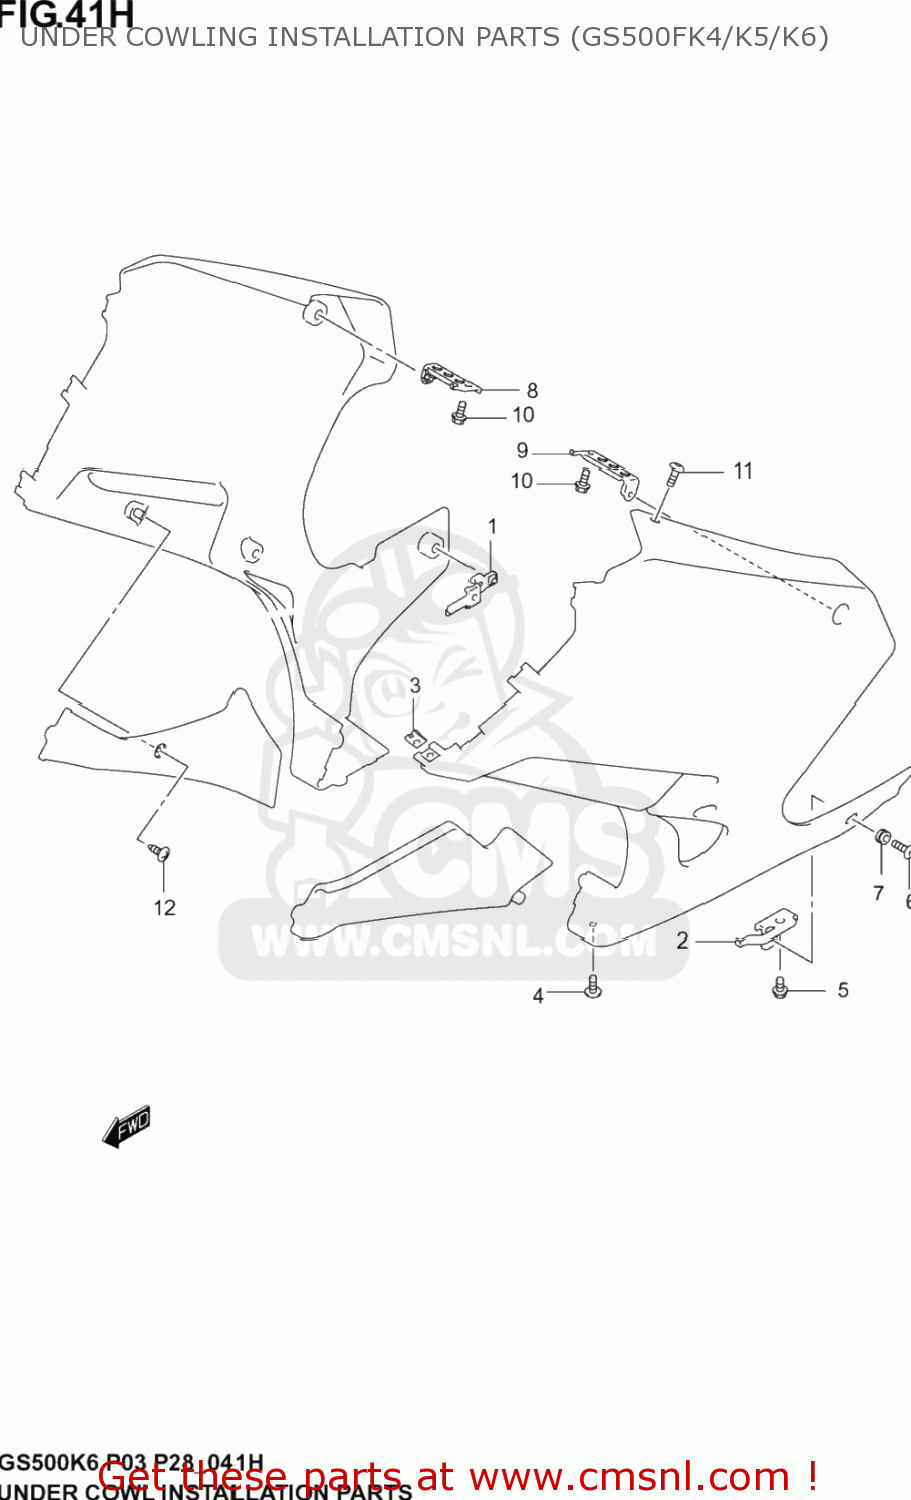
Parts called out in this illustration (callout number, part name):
1	BRACKET,LOWER
2	BRACKET, LOWER
3	NUT
4	CLIP
5	BOLT OIL LEVEL
6	SCREW(6X20)
7	CUSHION
8	BRACKET,REAR R
9	BRACKET,REAR L
10	BOLT OIL LEVEL
11	SCREW(5X16)
12	SCREW
